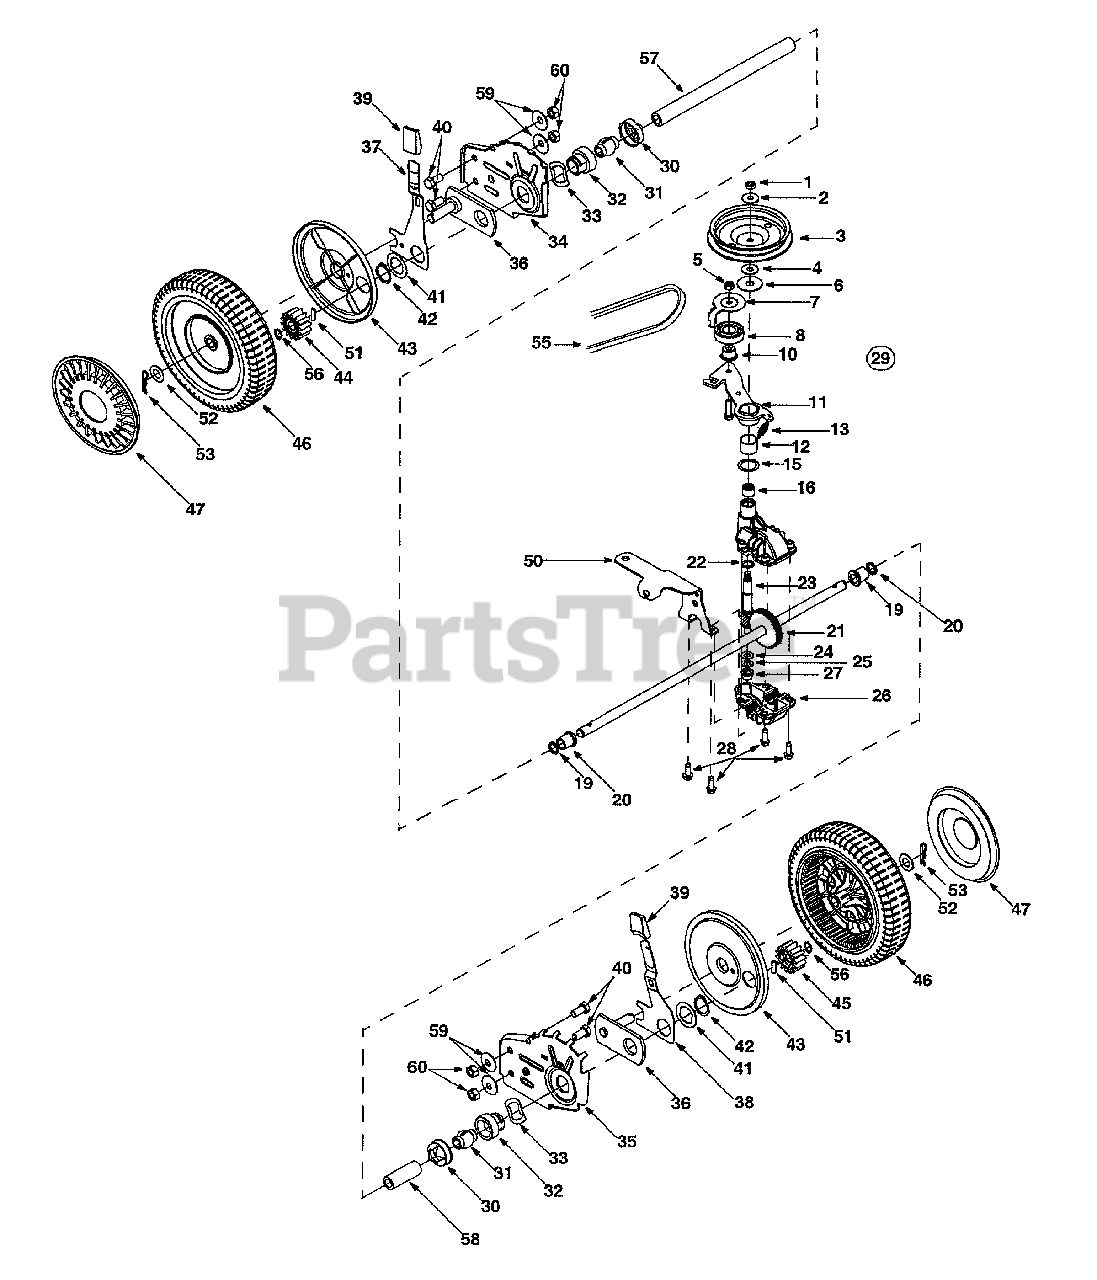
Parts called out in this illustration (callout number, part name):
1	Hex Jam Nut 5/16-24
2	Bell Washer .325 x .930 x .045
3	Pulley, 3.82 x .313 x .68
4	Bell Washer .325 x .930 x .045
5	Lock Nut 1/4-28
6	Flat Washer .442 x 1.38 x .060
7	Belt Keeper
8	Ball Bearing
10	Flange Spacer
11	Idler Bracket Assembly
12	Bearing Sleeve
13	Flat Washer .504 x .700 x.030
15	Flat Washer .865 x 1.145 x .030
16	Needle Bearing .438 x .625 x .500
19	Oil Seal .500 x .687 x .094
20	Flange Bearing
21	Output Shaft
22	Flat Washer .504 x .700 x .030
23	Pinion Shaft 10T
24	Thrust Washer .375 x .70 x .030
25	Thrust Washer .388 x .625 x .062
26	Lower Housing
27	Flange Bearing .378 x .531 x .370
28	Hex Screw w/Washer 1/4-20 x .750
29	Transmission Assembly Comp.
30	Bearing Retainer
31	Bearing Sleeve .50 I.D.
32	Bearing Support
33	Wave Washer 1.5 x 1.0 x .029
37	RH Front Lever
38	LH Front Lever
39	Knob
40	Hex Cap Screw 3/8-16 x .75
41	Washer DD 1.5" O.D.
42	Snap Ring 1.0 dia.
43	Wheel Dust Cap
44	Gear 14T R.H.
45	Gear 14T L.H.
46	Wheel, 8x2 x 1.75
47	Hubcap: Yellow
50	Cable Idler Bracket
51	Dowel Pin
52	Flat Washer 1/2 x 1.00 x .063
53	Cotter Pin .08 x 1.42
55	Belt
56	Snap Ring
57	Slev. Spacer
58	Slev. Spacer
59	Bell Washer
60	Hex Nut 3/8-16
